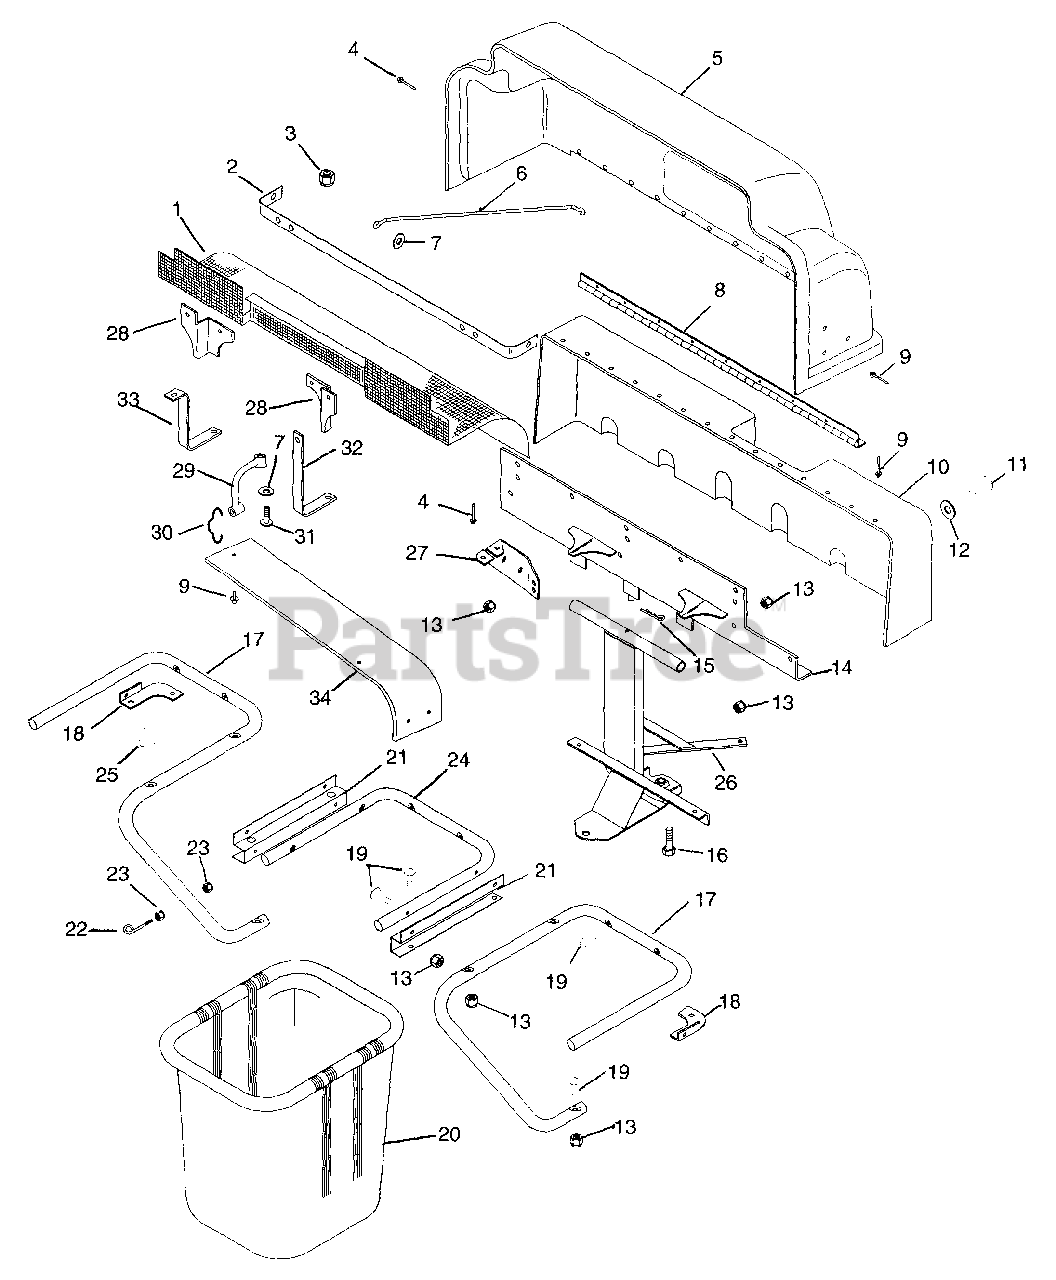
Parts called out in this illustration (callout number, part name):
2	SCREEN MOUNTING BRACKET
3	NUT-LK TOP 10-24 PL
4	RVT-POP.187X.527 DOME ST
5	HINGED COVER W/DECALS
7	WSHR-FL-STL .194X.492X.047 PL
8	HINGE- 2.0"X35.0"
9	RVT-POP .187X.402 DOME ST
10	STATIONARY COVER
11	BLT-HEX .31-18X.88 PL GR2
12	WSHR-FL-STL .344X1.125X.063PL
13	NUT-LK-NYL.312-18 PL
14	MOUNTING BRACKET
15	PIN-HAIR INT .08X.38X1.42 YWZC
16	BLT-HEX .50-13X1.25 PL GR2
17	RIGHT TUBE
17	LEFT TUBE
18	RH CORNER BRACKET
18	LH CORNER BRACKET
19	SCR-MCH .31-18X1.50 CROVCNTRS
20	GRASS BAGGER BASKET
21	TUBE BRACKET
22	EYEBOLT
23	NUT-LK-CTR .250-20 PL
24	CENTER TUBE
25	SCR-TAP .312-18X.50 HWH PL TR
26	BAGGER FRAME
28	BAFFLE LH
28	BAFFLE RH
29	BATTERY STRAP
31	SCR-MCH 10-24X.88 SLRH PL
32	BRACE
33	BRACE
34	BAFFLE
